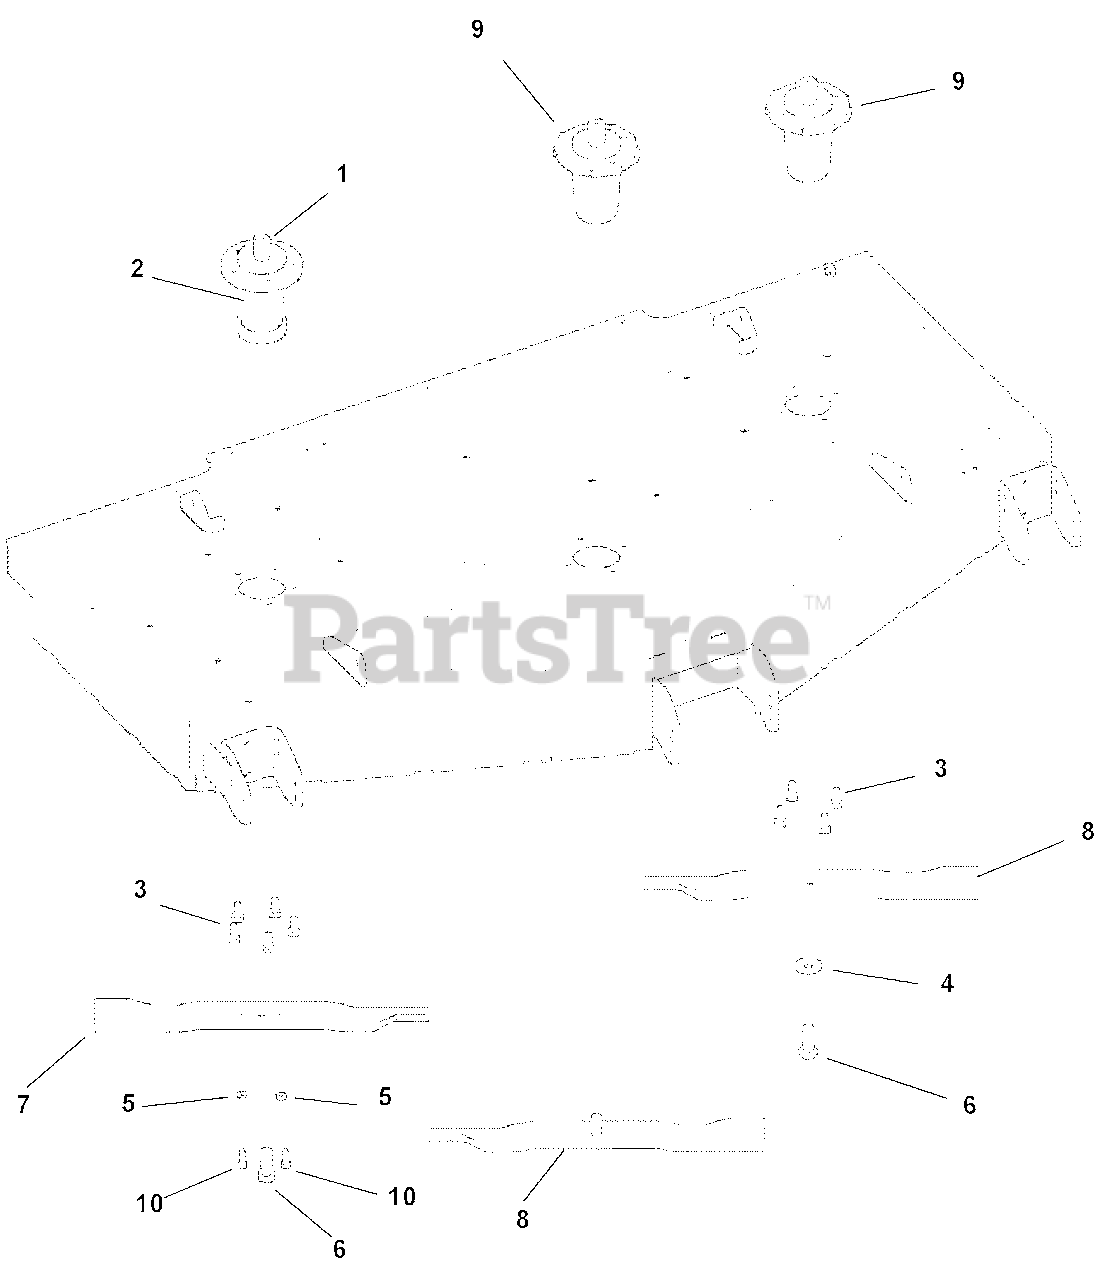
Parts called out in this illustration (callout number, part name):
1	Retainer, Grease
2	Spindle
3	Bolt, Hex .375-16 x 1
4	Washer, Bellville .63 x 1.625 x .14
5	Lock Washer, Spring Regular
6	Bolt, Hex .62-18 x 1.75
7	Blade, 20.83" Mower (Counterclockwise Rotation)
8	Blade, 20.83"
9	Housing, Spindle (G5000)
10	Bolt, Hex .31-18 x 1.00 Grade 5
